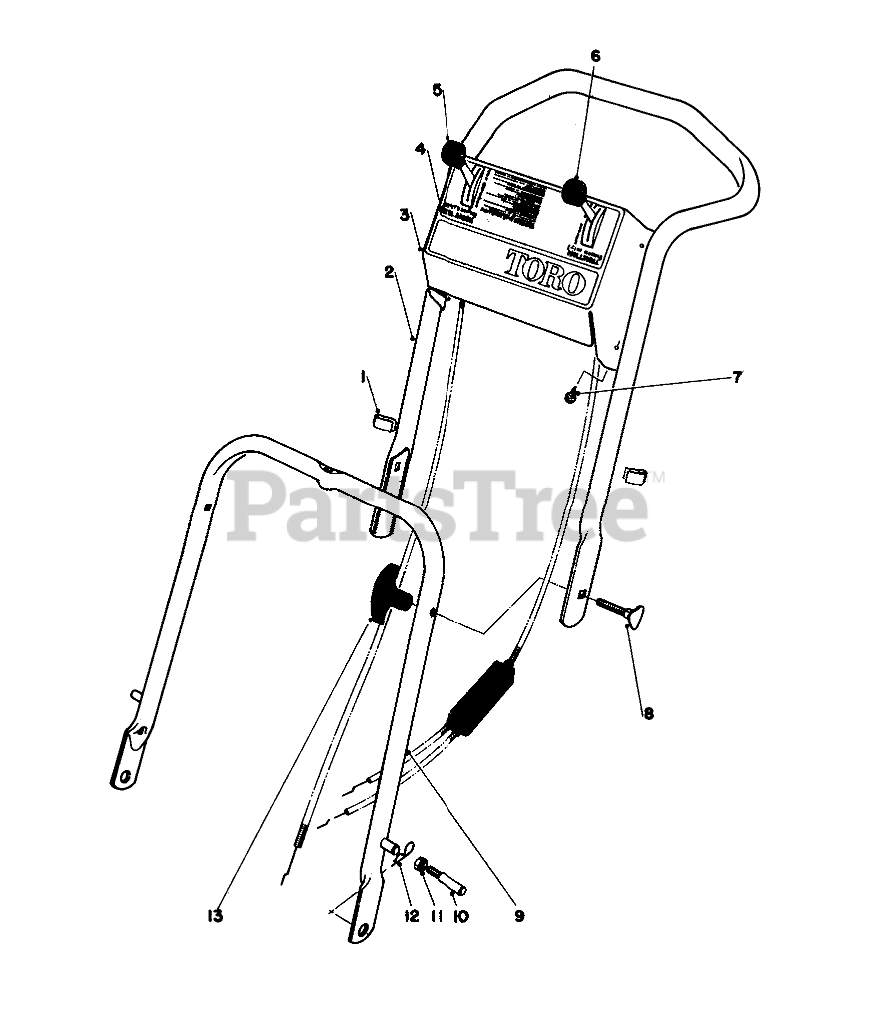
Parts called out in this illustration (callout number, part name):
1	BOWDEN CLIP
2	UPPER HANDLE
3	Control Plate
4	Decal Control Plate
5	Control Throttle
6	Traction Control
7	SCREW-HWHTF
8	HANDLE SCREW
9	Lower Handle
10	HANDLE PIN
11	Nut
12	PIN-COTTER, HAIR
